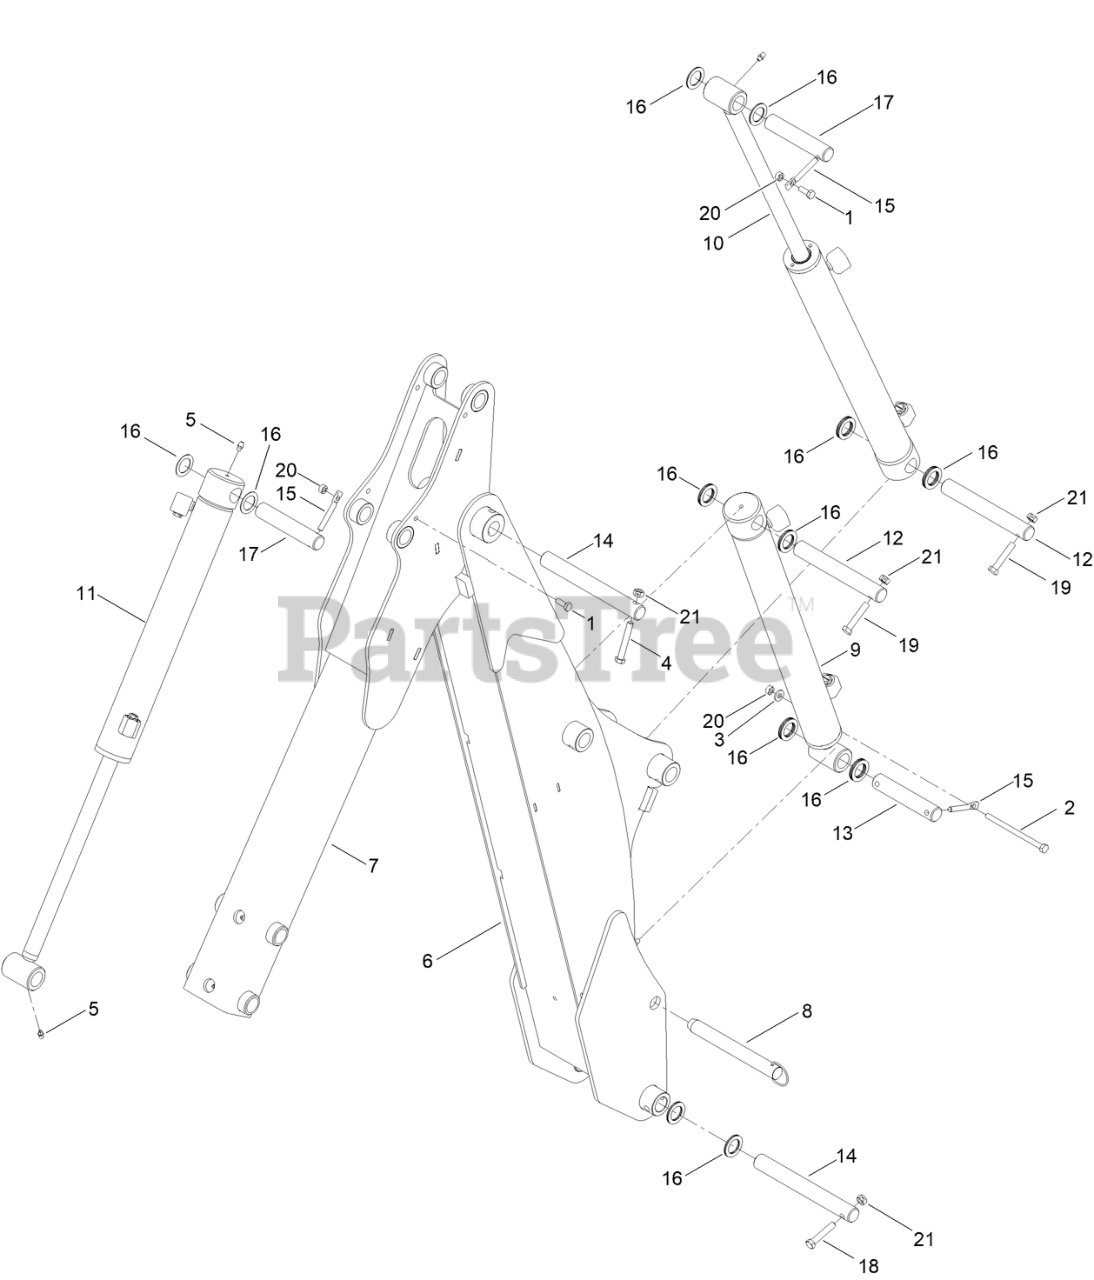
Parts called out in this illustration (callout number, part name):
1	SCREW-HH
2	SCREW-HH
3	WASHER
4	SCREW-HH
5	FITTING-GREASE
6	BOOM ARM-INNER
7	BOOM ARM-OUTTER
8	LOCKING PIN-BOOM INNER
9	CYLINDER-BOOM
10	CYLINDER-BOOM
11	CYLINDER-BOOM
12	PIN-BOOM CYLINDER
13	PIN-BOOM CYLINDER
14	PIN-BOOM CYLINDER
15	LOCK PIN-CYLINDER
16	WASHER
17	PIN-CYLINDER
18	SCREW-HH
19	SCREW-HH
21	NUT-LOCK
